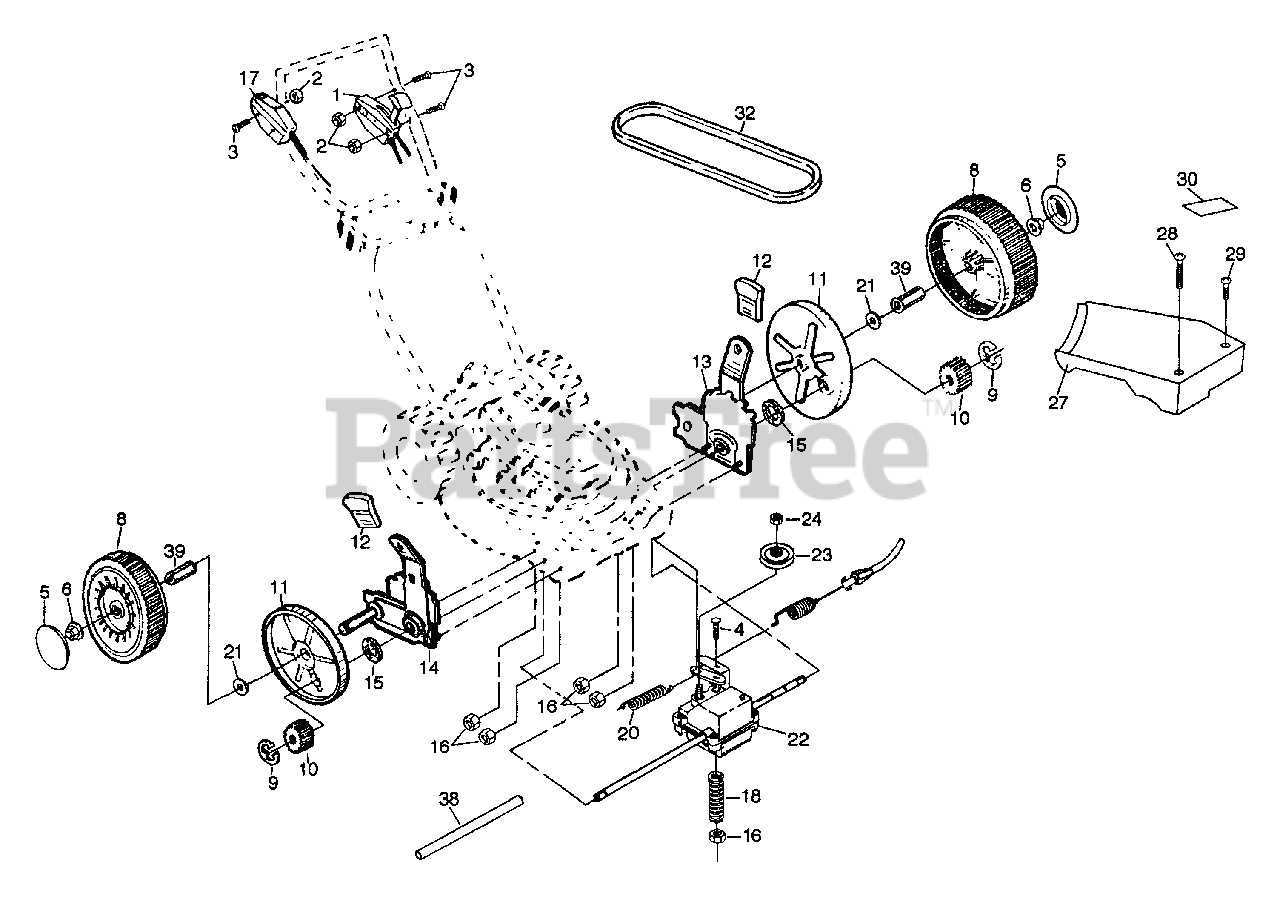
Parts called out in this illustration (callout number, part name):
1	Drive Control
2	Locknut #10-24
3	Hex Washer Head Screw 1/4-20 x 2.12
4	Carriage Bolt 1/4-20 x 2
6	Flange Locknut
8	Wheel & Tire Assembly
11	Dust Cover
12	Selector Knob
13	Wheel Adjuster Assembly Left)
14	Wheel Adjuster Assembly (Left)
15	Felt Washer
16	Locknut
17	Engine Zone Control Cable
22	Gear Case Assembly
23	Drive Pulley
24	Locknut
27	Drive Cover
28	Pan Head Machine Screw #10-24 x 2-3/4
29	Pan Head Machine Screw #10-24 x 1-3/4
30	Drive Cover Decal
32	V-Belt
38	Drive Shaft Cover
39	Wheel Bushing
